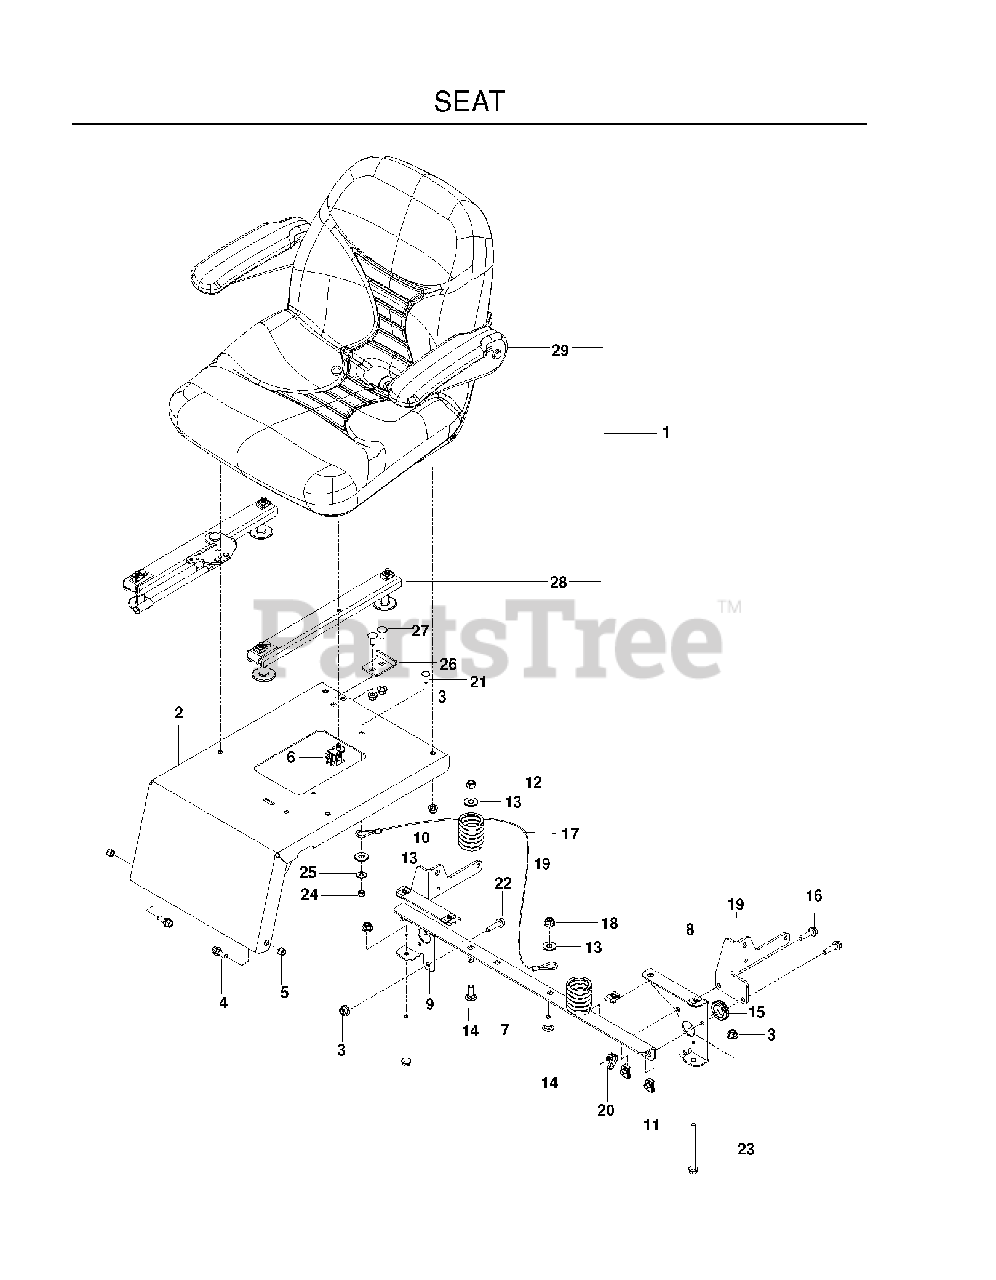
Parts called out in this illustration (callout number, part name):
1	SEAT
2	KIT.SEAT.MOUNT.W/DECAL
3	5/16-18 NYLOC FLANGE NUT
4	SB 5/16-18 HEX HD GD5, BLK ZN
5	NUT 5/16 NYLOC
6	SEAT SWITCH
7	SUPPORT, SEAT
8	SUPPORT, LT, BLK
9	SUPPORT, RT, BLK
10	SPRING, SEAT
11	U-CLIP 5/16-18 NUT RETAINER
12	NUT 3/8-16 NYLOC
13	RP WASHER 3/8 FLAT
14	RHSNB 3/8C X 1
15	RUBBER GROMMET
16	HHFS 5/16-18 X 1.25 TPBLT GD 5
17	SEAT LANYARD
18	NUT 3/8-16 HEX FLG NYLOC ZD
19	MOUNT, SEAT BELT, BLACK
20	TIE WRAP, 8-3/8", W/CLIP
21	RHSNB 1/4C X 3/4
22	HHFS 5/16-18 X 3/4
23	HHFS 5/16-18 X 3 3/4
24	RP_NUT 1/4-20 NYLOC
25	WASHER 1/4 FLAT
26	STOP, SEAT - BLACK
27	RHSNB 5/16-18 X 3/4
28	TRACK ADJUSTMENT KIT
29	ARMREST KIT, LT SQUARE END
